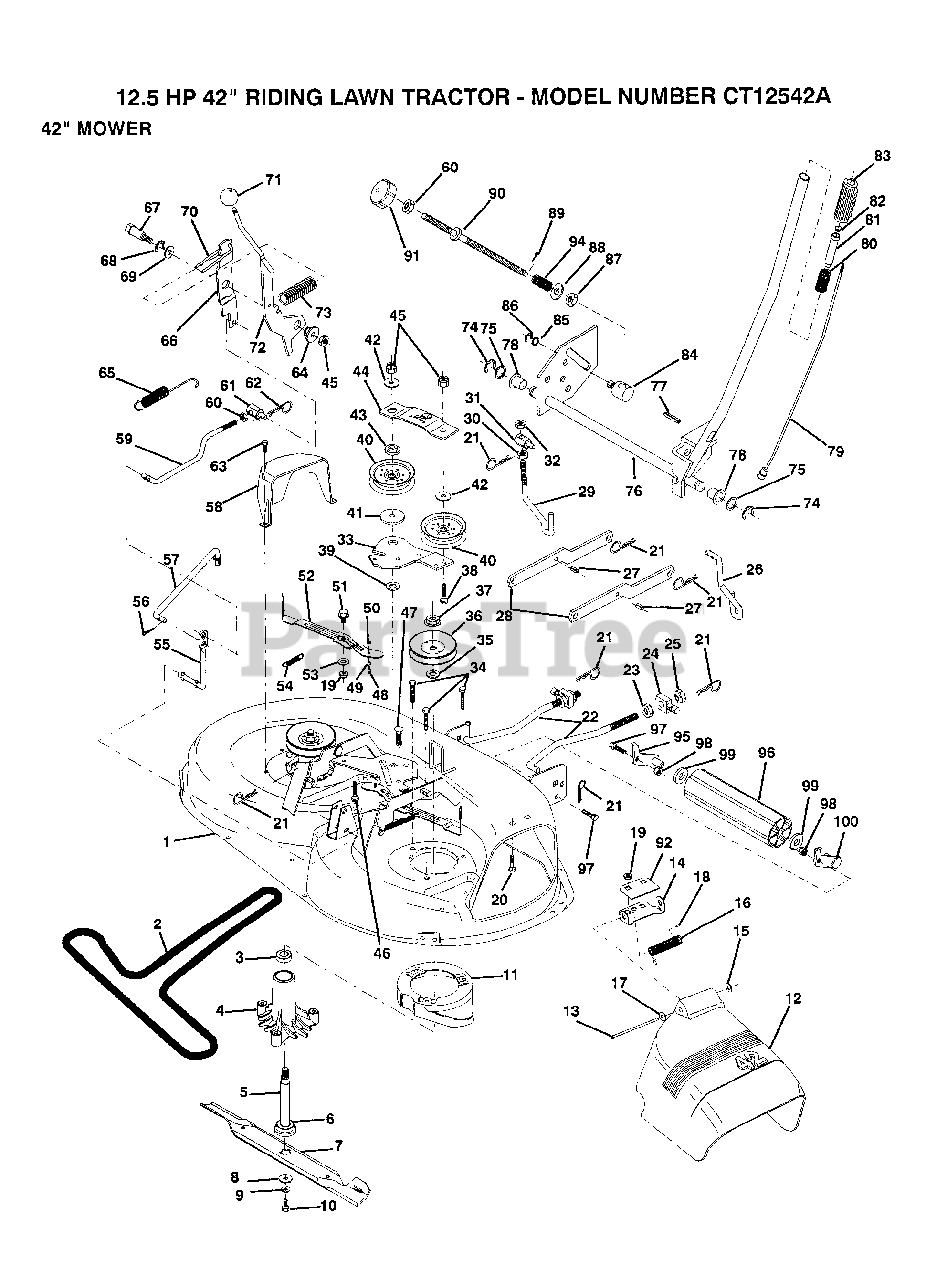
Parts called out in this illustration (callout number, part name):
2	BELT-V.92.4.MWR
3	BEARING
4	HSG ASM MANDREL
6	BEARING.BALL
8	WASHER BLADE
10	BLADE BOLT
12	DEFLECTOR.SHIELD
13	HINGE ROD
14	DEFLECTOR BRKT
15	NUT PUSH M
16	SPRING TORSION
17	WASHER
18	CAP-SLEEVE LT
20	BOLT
22	LINK.FRONT
23	NUT
24	TRUNION
25	NUT.LK.W/WSH.1/2.
26	LINK LIFT RH
27	SPRING PIN
29	LIFT LINK LH
30	NUT
33	IDLER ARM
35	WASHER
38	BOLT
39	HARDENED WASHER
40	FLAT IDLER PULLEY
41	SPACER RETAINER
42	WASHER GT
43	RETAINER SPACER
44	IDLER ARM STIFF
46	BOLT CARRIAGE
47	XMAS TREE FASTNER
48	SHOULDER BOLT
50	LOCKNUT
52	BRAKE PAD ARM ASM
53	HARD SMALL WASHER
54	SPRING EXTENSION
55	PIVOT ROD
57	CLUTCH ROD SECOND
60	NUT
61	TRUNION
62	RETAINER M
63	SCREW LT
64	BUSHING
65	RETURN SPRING
66	CLUTCH ARM SECOND
67	SHOULDER BOLT
68	RING
69	WASHER
70	SPRING KEEPER
72	CLUTCH ARM PRI AS
75	WASHER
77	PIN-GROOVE LT
78	NYLON BEARING
83	GRIP
84	TRUNION LT
85	WASHER
86	KLIP RING
87	NUT T
88	WASHER
92	STIFFENER BRKT
94	SPRING T
97	BOLT
99	WASHER
